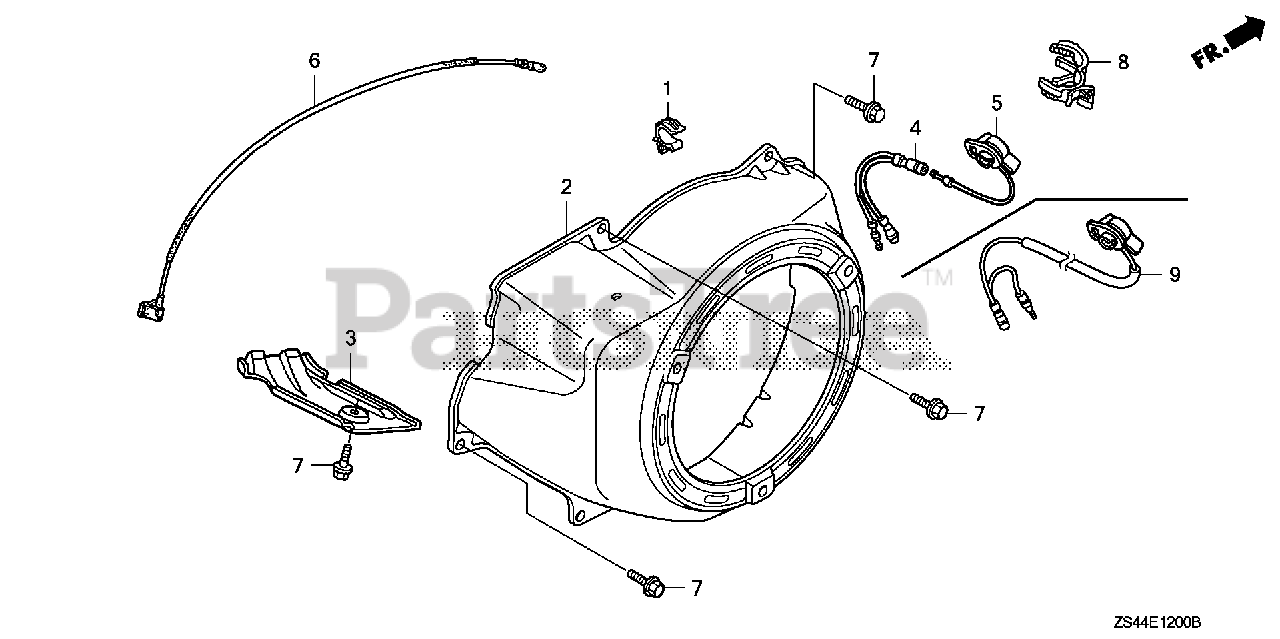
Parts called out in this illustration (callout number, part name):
1	CLIP, TUBE
2	COVER, FAN *NH1* (BLACK)
6	WIRE, STOP SWITCH (430MM)
7	BOLT, FLANGE (6X12) (CT200)
8	CLIP, HARNESS
9	SWITCH ASSY., ENGINE STOP
